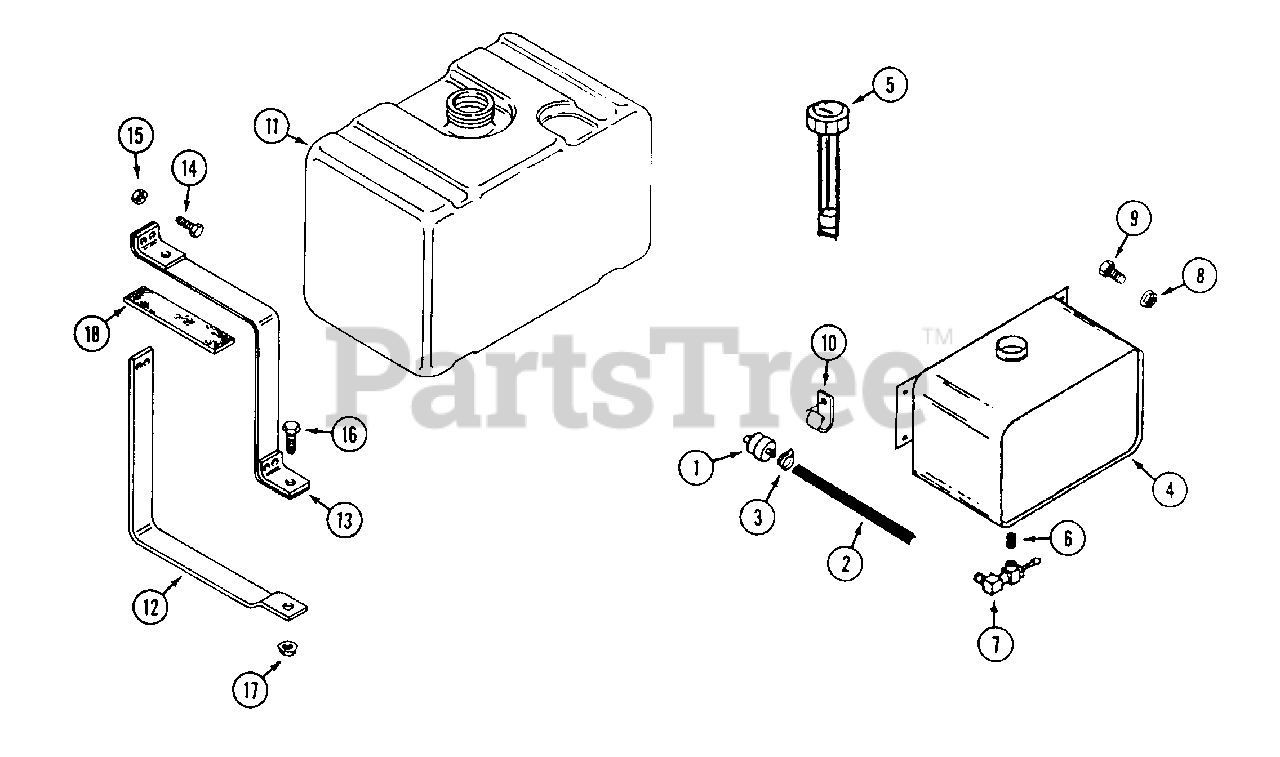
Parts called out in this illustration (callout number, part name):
1	FILTER - fuel
2	HOSE - fuel (cut to length)
4	TANK- fuel (1-3/4" filler tube) metal
5	CAP - fuel tank (with gauge) (1-3/4" threads)
6	NIPPLE - pipe 1/8"
7	VALVE - shut off
8	NUT - 1/4" - 20 flange lock
9	BOLT - 1/4" - 20 x 1/2"
9	BOLT - 1/4" - 20 x 3/4"
10	CLIP - "J" fuel line
11	TANK - fuel (2-1/4" filler tube) (plastic)
11	TANK - fuel (1-3/4" filler tube) (plastic)
12	BRACKET - fuel tank
13	STRAP - fuel tank
14	BOLT 1/4" - 20 x 1-1/2"
15	NUT 1/4" - 20 lock
16	BOLT - 5/16" - 18 x 1"
17	NUT - 5/16" - 18 flange lock
